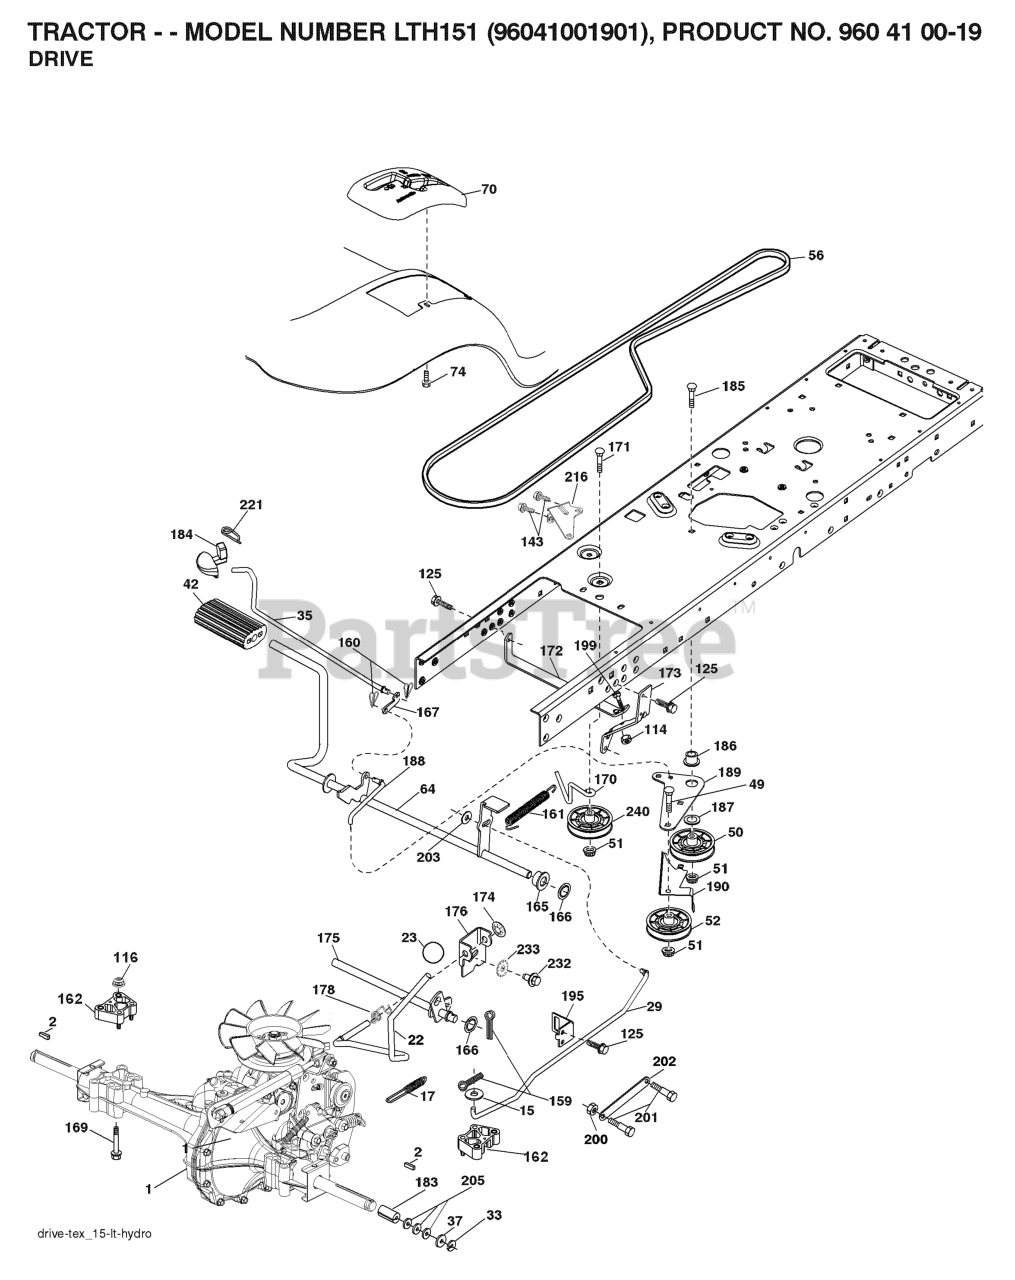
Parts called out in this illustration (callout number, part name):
2	SQUARE KEY
15	WASHER
17	SPRING.BRAKE.HG3000/3500
22	ROD.SHIFT.FENDER.TLT.2006
23	KNOB.DUCKHEAD.1/2
29	ROD.BRAKE.HG-0510
35	ROD.CNTRL.PARK.PREDATOR.LT.TEX
42	PEDAL COVER T
50	IDLER.FLAT.910.OFFSET
51	NUT LOCK FLG 3/8-16 UNC
52	IDLER.V-GROOVE.910.OFFSET
64	SHAFT.ASM.PEDAL.BRAKE.
70	CONSOLE SHIFT
74	SCREW.HI-LO.CONSOLE
114	NUT.71038.31-18.HEX.NYLOCK
116	NUT LOCK HEX FLANGE 5/16-18
125	SCREW
143	Screw 5/16-18 x 1/2 Hex, Self Tapping 5/16-18 x 1/2
159	COTTER PIN
160	RETAINER CLIP
161	SPRING.RETURN.CLUTCH.2006
162	SPACER.TRANSAXLE.18&22
165	BUSHING.SHAFT.BRAKE.HAND
166	NUT.PUSH.625.2006
167	LATCH.BRAKE.SPRING
169	BOLT.HEX.FLNG.5/16-18X3.75
170	KEEPER.V-IDLER.CENTER.
172	STRAP.TRQ.LH.FS.HG0510
173	STRAP TORQUE RH
174	NUT.PUSH.500.2006
175	SHAFT.ASM.SHFT.HG0510/
176	ARM.CLEVIS.ROD.SHIFT
178	SPRING.SHIFT.GT2006
183	SPACER AXLE
184	HANDLE PARKING BRAKE
186	SPACER.RETAINER
187	WASHER 12/32X2X10GA
188	RP.LINK.CLUTCH.GROUND.DRIVE
189	BELLCRANK.GROUND.DRIVE.TEX.
190	KEEPER.BELLCRANK.DRIVE
195	BRKT.ROD.BRAKE.18/20/2
200	NUT.CENTERLOCK.5/16-
201	BOLT SHOULDER 5/16-18 UNC
202	LINK TRANS
203	WASHER
216	BRACKET.PULLEY.IDLER.W/TEX
221	RETAINER.SPRING.CLIP.H
232	BOLT FIN HEX 7/16-14 X 1
233	WASHER SERRATED
240	IDLER.V-GROOVE.1.688.OFFSET
